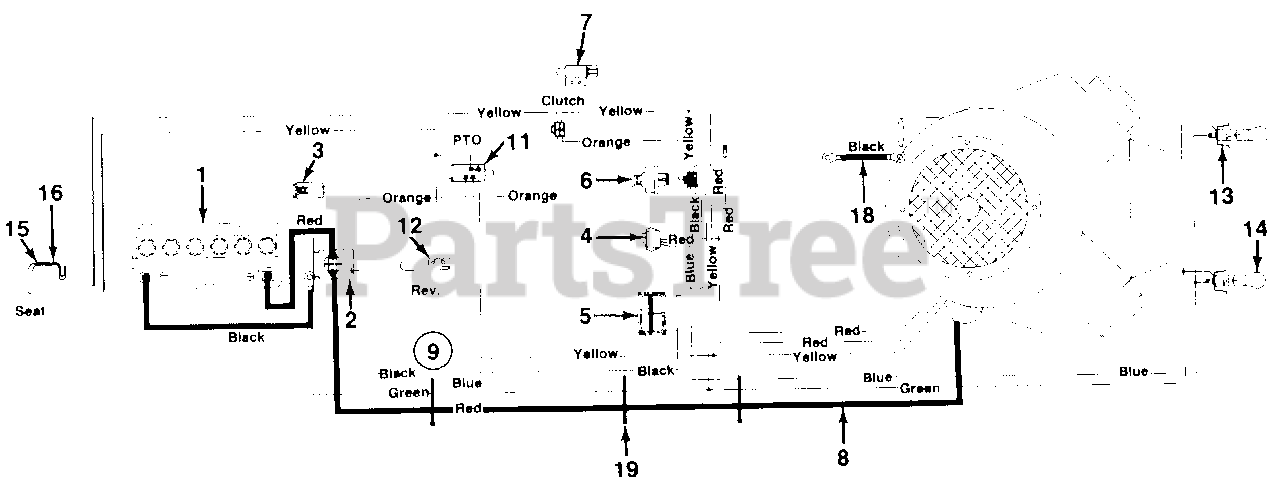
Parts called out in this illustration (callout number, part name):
1	Battery (275 Cold Crank Amps)
2	Solenoid
3	Fuse 20 Amp.
4	Light Switch
5	Ammeter
6	Ignition Switcht
7	Safety Switch
8	Electric Wire 30" Lg.
9	Wire Harness
11	Safety Switch
12	Safety Switch
13	Socket
14	Bulb
15	Safety Switch
16	Safety Switch
18	Ground Wire-7.5" Lg.
